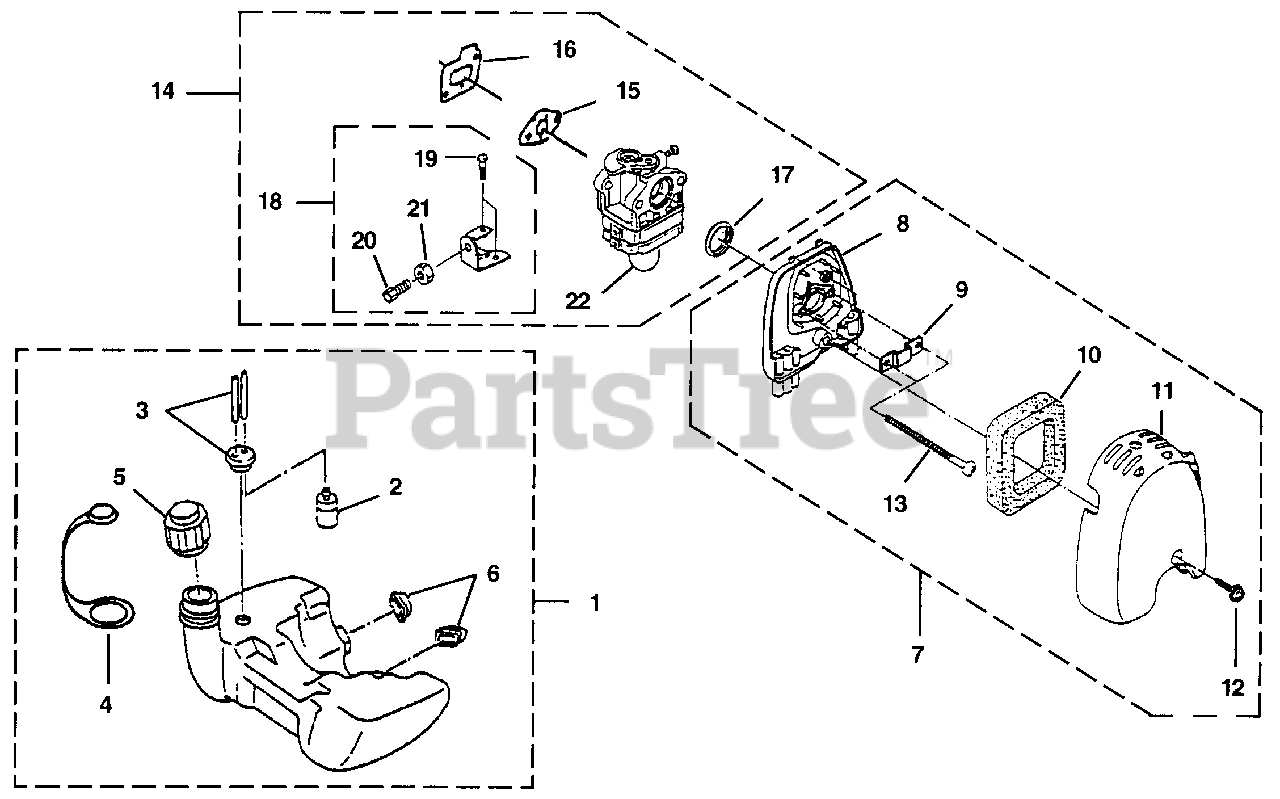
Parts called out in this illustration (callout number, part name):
1	FUEL TANK ASSEMBLY
2	FILTER-Fuel
4	CAP-Retainer
5	CAP-Fuel
6	RUBBER BUMPER KIT
7	AIR FILTER ASSEMBLY
8	BODY-Air Filter
9	PLATE-Air Filter
10	FILTER-Air
11	COVER-Air Filter
12	SCREW ASSEMBLY (M5 x 14)
13	SCREW (M5 x 50)
14	CARBURETOR ASSEMBLY
15	GASKET-Carburetor
16	GASKET-Heat Dam
17	RING-Packing
18	CABLE BRACKET ASSEMBLY
19	SCREW-Throttle Collar (M5 x 18)
20	SCREW-Cable Adjust
21	NUT-Cable Adjust
22	PRIMER BULB
